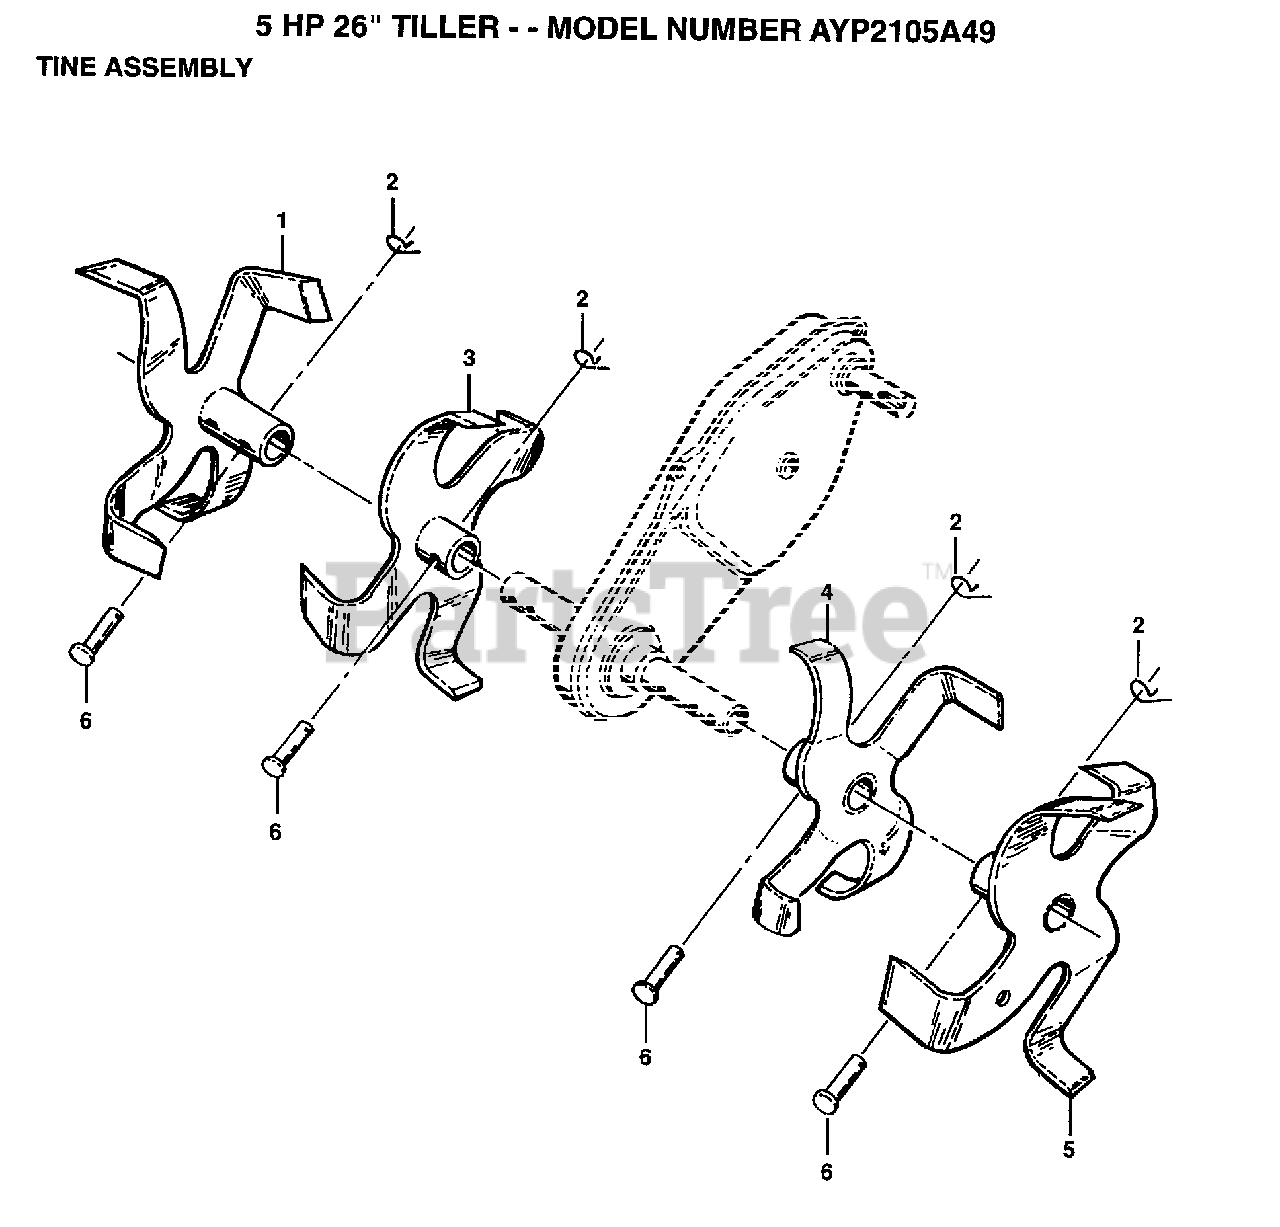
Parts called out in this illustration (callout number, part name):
1	TINE WELDMENT TI
2	RETAINER.SPRING
3	TINE TI
4	TINE TI
5	TINE WELDMENT TI
6	RIVET.PAN HD.1.75
